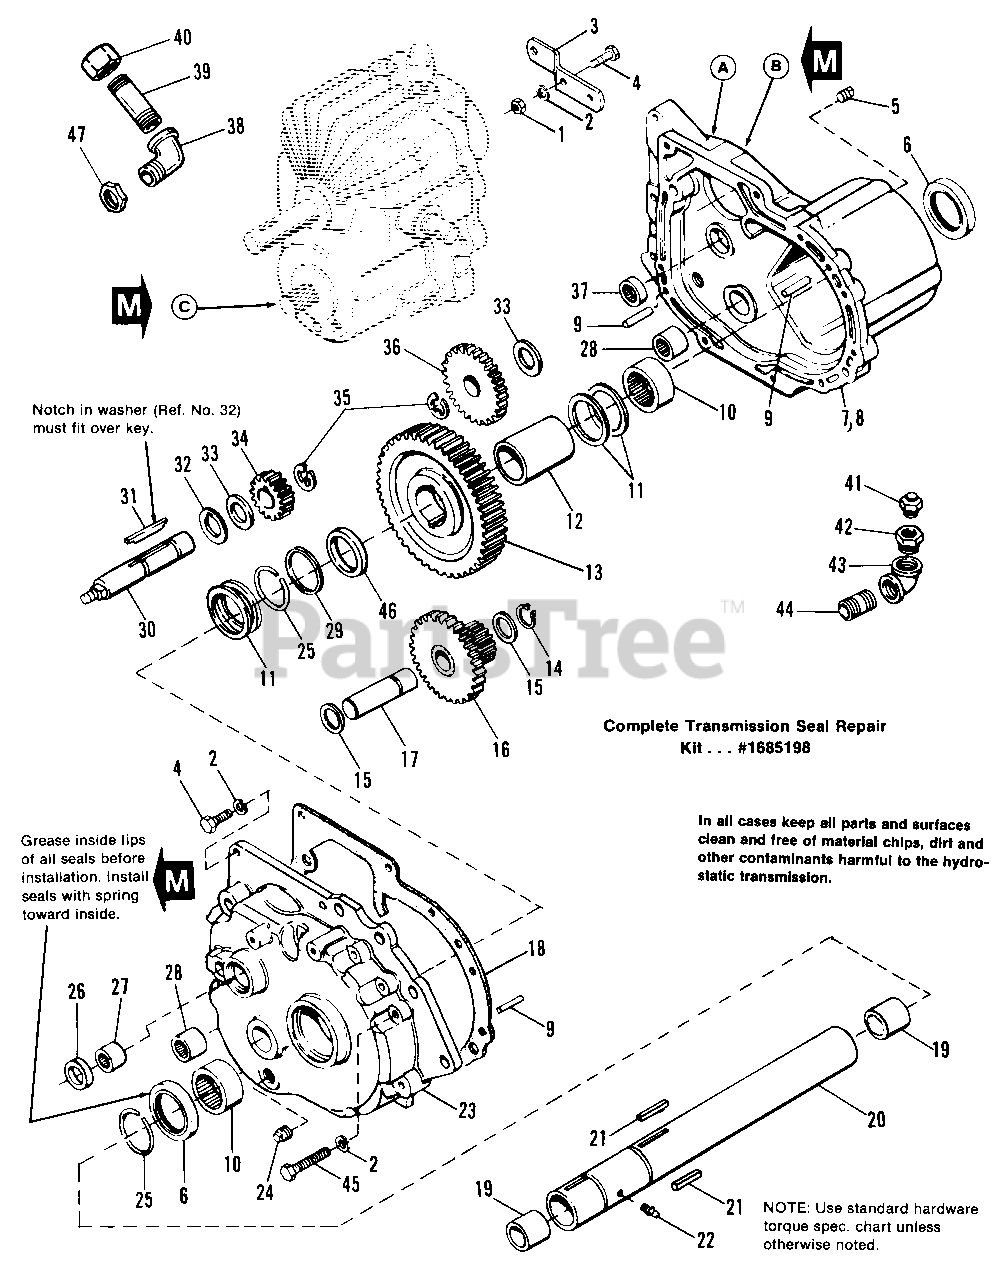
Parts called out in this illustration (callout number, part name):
1	NUT, Hex, Full, 5/16-18
2	LOCKWASHER, 5/16
3	SUPPORT, Spring
4	CAPSCREW, Hex Hd., 5/16-18 x 1
7	CASE ASSY., w/Bearings
9	PIN, Roll, 3/8 x 1
12	SPACER, Axle, LH
13	GEAR, Drive
14	RING, Retaining
16	PINION & SHAFT ASSY.
17	SHAFT, Intermediate
20	TUBE ASSY, Axle
22	FITTING, Grease
23	COVER ASSY., Grease Case w/Bearings
24	PLUG, Pipe
25	RING, Retaining
28	BEARING, Needle
30	SHAFT, Brake
35	RING, Retaining
37	BEARING, Needle
38	ELBOW, Street
39	NIPPLE, Pipe
41	VALVE, Relief
42	BUSHING, Pipe
43	ELBOW, Pipe
44	NIPPLE, Pipe
45	CAPSCREW, Hex Hd., 5/16-18 x 2
46	SPACER, Axle, RH
47	LOCKNUT, 3/8, Rigid Conduit
